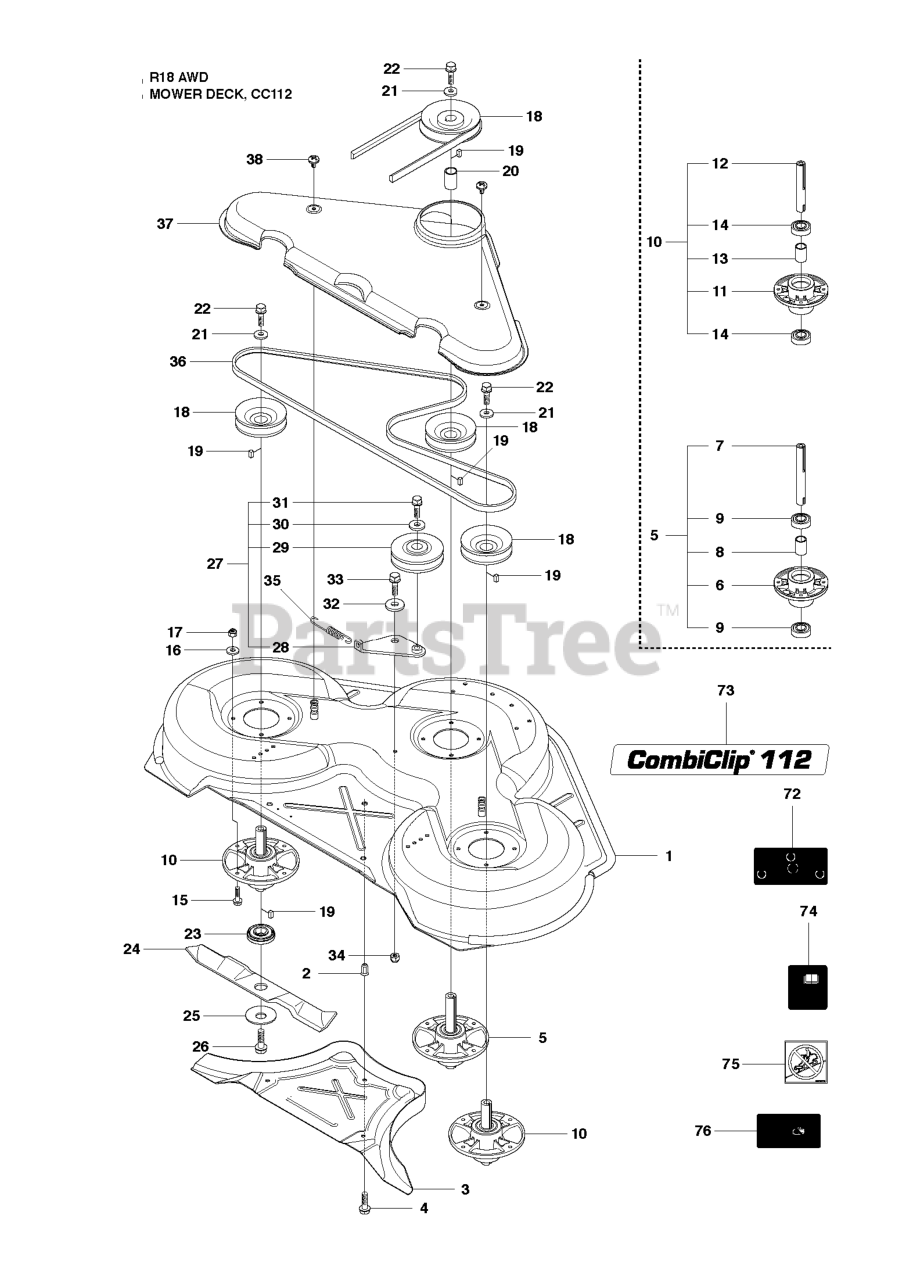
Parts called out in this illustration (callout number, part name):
1	CUTTING DECK
5	SPINDLE ASSY
6	BEARING HOUSING
10	RP SPINDLE ASSY
11	BEARING HOUSING
16	WASHER BRB 8.4X17
17	LOCKNUT M8
25	WASHER
27	BELT TENSIONER ASSY
28	BELT TENSIONING ARM
32	WASHER
34	LOCKNUT M8
36	BELT
37	BELT COVER
